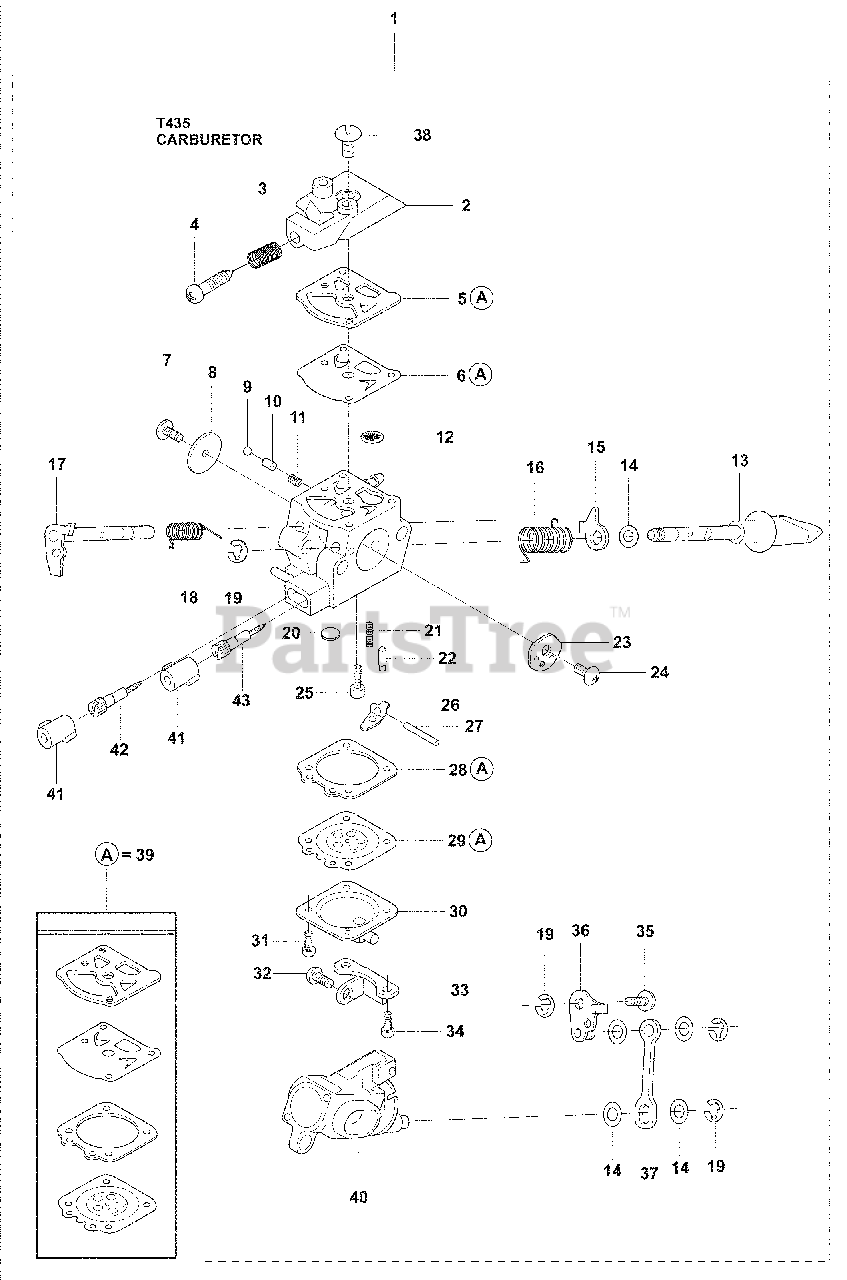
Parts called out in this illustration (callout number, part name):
1	Carburettor
3	Spring, Idle
6	Diaphragm pump
8	Valve, throttle
9	Ball
10	Piston
12	Screen
13	Choke shaft
16	Spring choke shaft
17	Throttle schaft
18	Spring, throttle latch
19	Clip
22	Valve, inlet
23	Valve, choke
29	Diaphragm carburetor
36	Throttle link
39	Diaphragm kit
40	Body air valve
